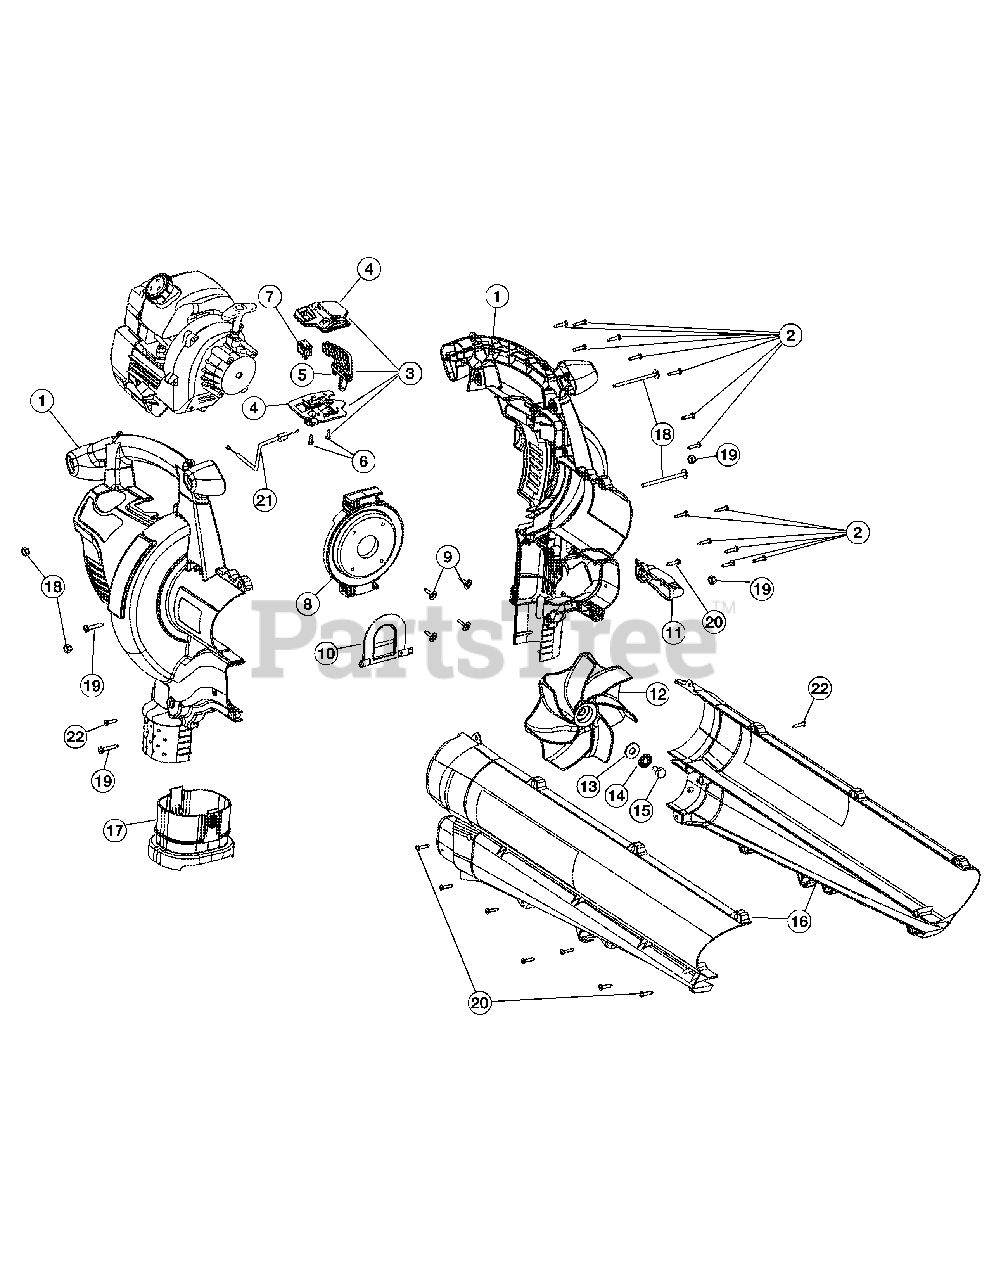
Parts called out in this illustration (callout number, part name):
1	Engine Cover Assembly
2	Cover Screw
3	Throttle Control Assembly
4	Throttle Control Plates
5	Throttle Control Lever
6	Screw, Plastic
7	Rocker Switch Assembly
8	Engine Mounting Plate
9	Screw, Plastic
10	Mode Control Flapper
11	Mode Control Lever
12	Impeller Blade
13	Washer
14	Lock Washer
16	Blower/Vac Tube Assembly
17	Vacuum Bag Adapter
18	Mounting Plate Hardware
19	Blower.Vac Tube Mounting Hardware
21	Throttle Cable
